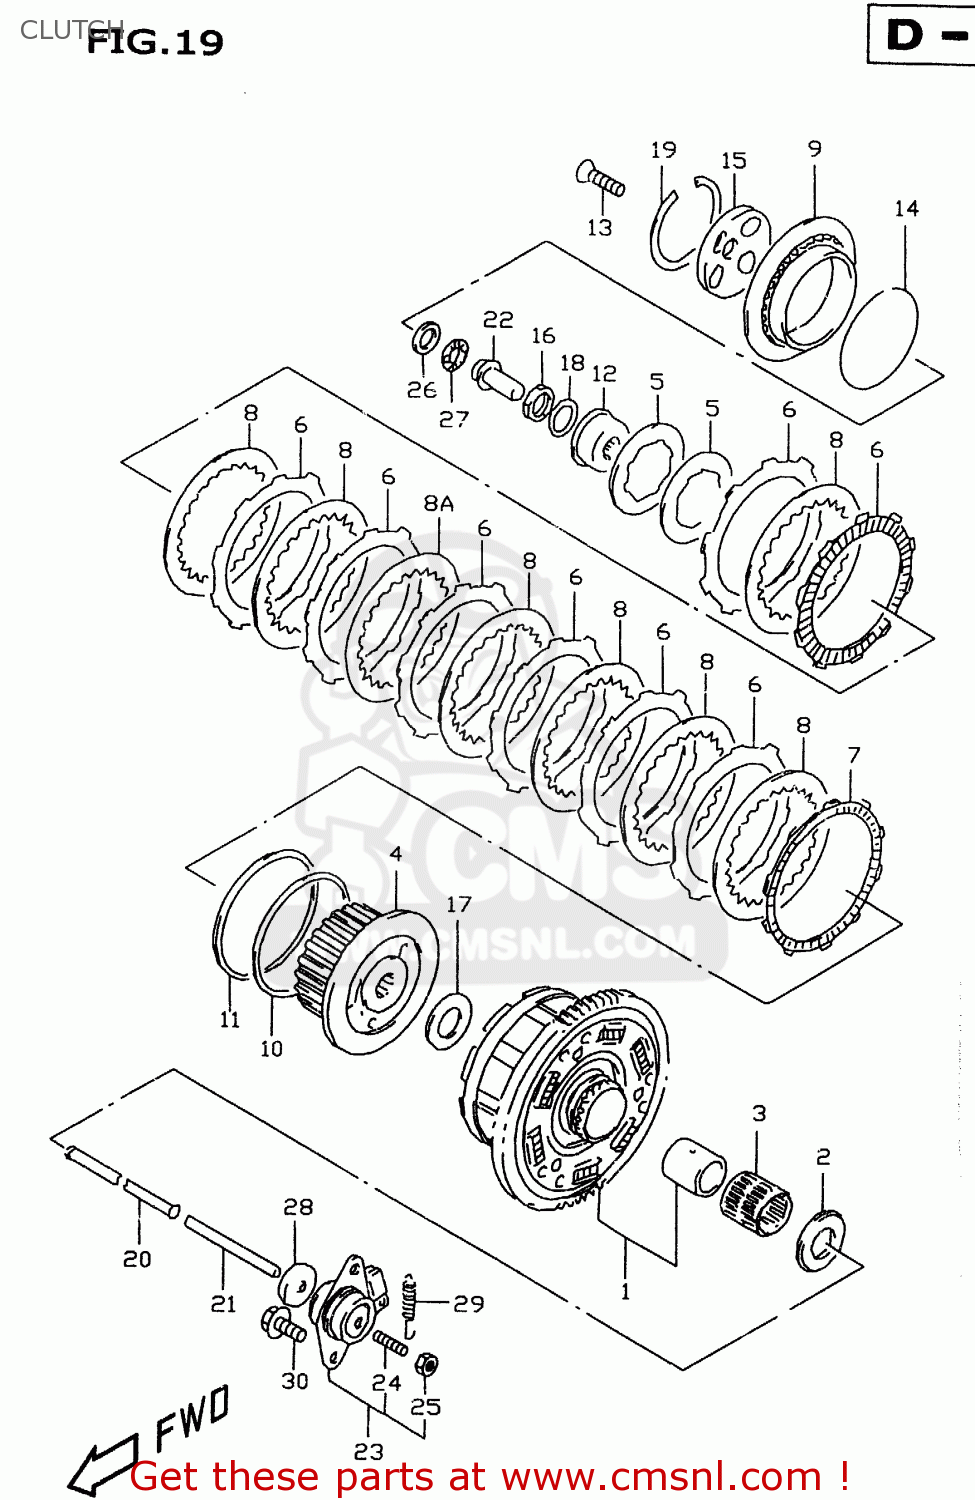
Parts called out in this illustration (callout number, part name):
1	GEAR ASSY,PRI DRIVEN
2	WASHER(25X54X2.5)
3	BEARING(35X40X35.8)
4	HUB,CLUTCH SLEEVE
5	SPRING,CLUTCH
6	PLATE,CLUTCH DRIVE NO (NAS)
7	PLATE,CLUTCH DRIVE
8	PLATE,CLUTCH DRIVEN NO.1
8A	PLATE,CLUTCH DRIVEN NO.2
9	DISC,CLUTCH PRESSURE
10	SEAT,CLUTCH PLATE WAVE WASHER
11	WASHER,CLUTCH PLATE WAVE
12	HOLDER,CLUTCH SPRING
13	SCREW,CLUTCH SPRING HOLDER
14	SEAT,CLUTCH SPRING
15	LIFTER,CLUTCH PRESSURE DISC
16	NUT
17	WASHER
18	WASHER
19	CIRCLIP
20	ROD,CLUTCH
21	ROD,CLUTCH PUSH,L
22	PIECE,CLUTCH PUSH
23	SCREW ASSY,CLUTCH RELEASE
24	SCREW(6X25)
25	NUT
26	WASHER(15.5X28X1)
27	BEARING(15X28X2)
28	SEAL,OIL(6X34X5.5)
29	SPRING
30	BOLT
